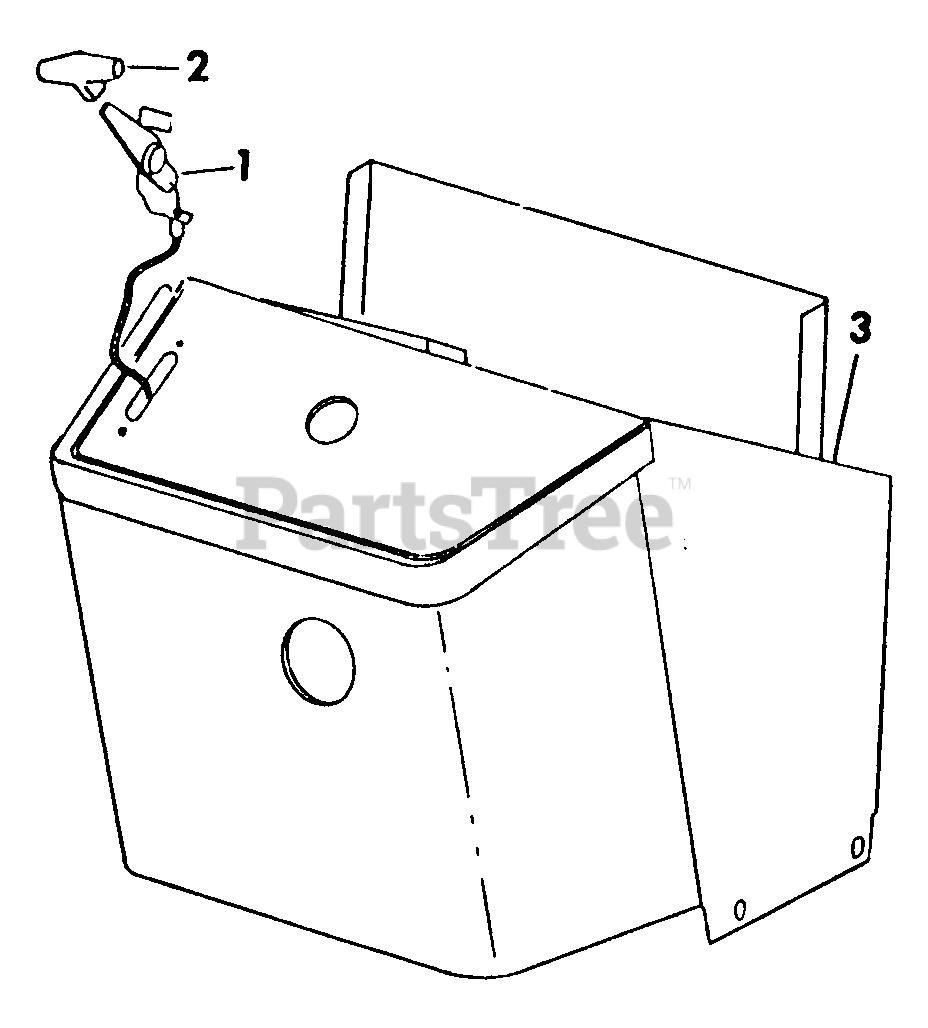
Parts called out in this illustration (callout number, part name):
1	Control Assy, Throttle
2	Knob, Throttle Control
3	Pedestal Assy
